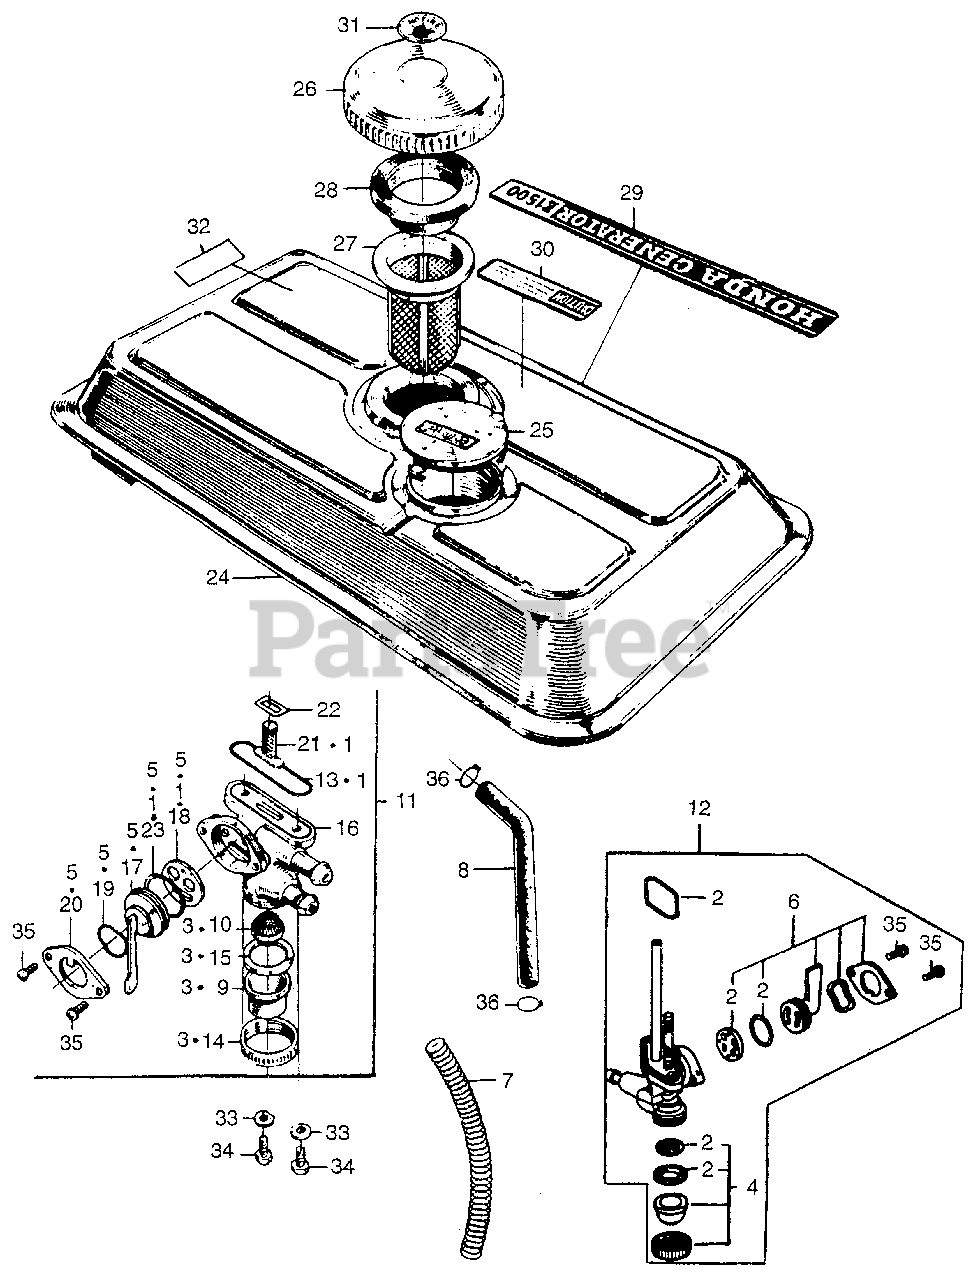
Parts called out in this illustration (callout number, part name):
1	GASKET SET, VALVE
3	CAP SET, STRAINER (ITEM #14 NOT INCLUDED. IT'S NO LONGER AVAILABLE.)
5	LEVER SET, VALVE (NOT AVAILABLE)
7	SPRING, FUEL TUBE (NOT AVAILABLE)
8	TUBE, FUEL (NOT AVAILABLE)
9	BOWL, FUEL
10	ELEMENT (NOT AVAILABLE)
11	PETCOCK ASSY. (NOT AVAILABLE)
13	O-RING (NOT AVAILABLE)
14	NUT, RING (NOT AVAILABLE)
15	GASKET, FUEL STRAINER CUP
16	BODY, PETCOCK (NOT AVAILABLE)
17	LEVER, PETCOCK (N/A: SEE ASSEMBLY)
18	GASKET, VALVE (NOT AVAILABLE)
19	SPRING, LEVER (NOT AVAILABLE)
20	PLATE, LEVER STOP (N/A: SEE ASSEMBLY)
21	FILTER, CHECK (NOT AVAILABLE)
22	GASKET, FILTER (N/A: SEE ASSEMBLY)
23	O-RING (21MM)
24	TANK, FUEL *NH31* (MCKINLEY WHITE) (NOT AVAILABLE)
25	COVER, PLUG *Y3L* (IVORY WHITE) (NOT AVAILABLE)
26	CAP, FUEL TANK
27	FILTER, FUEL
28	GASKET, FUEL FILTER (NOT AVAILABLE)
30	MARK A, CAUTION
31	MARK, TANK CAP CAUTION
33	GASKET, FIBER (6MM)
34	BOLT, HEX. (6X16)
35	SCREW, PAN (3X6)
36	CLIP, TUBE (C11) (NOT AVAILABLE)
